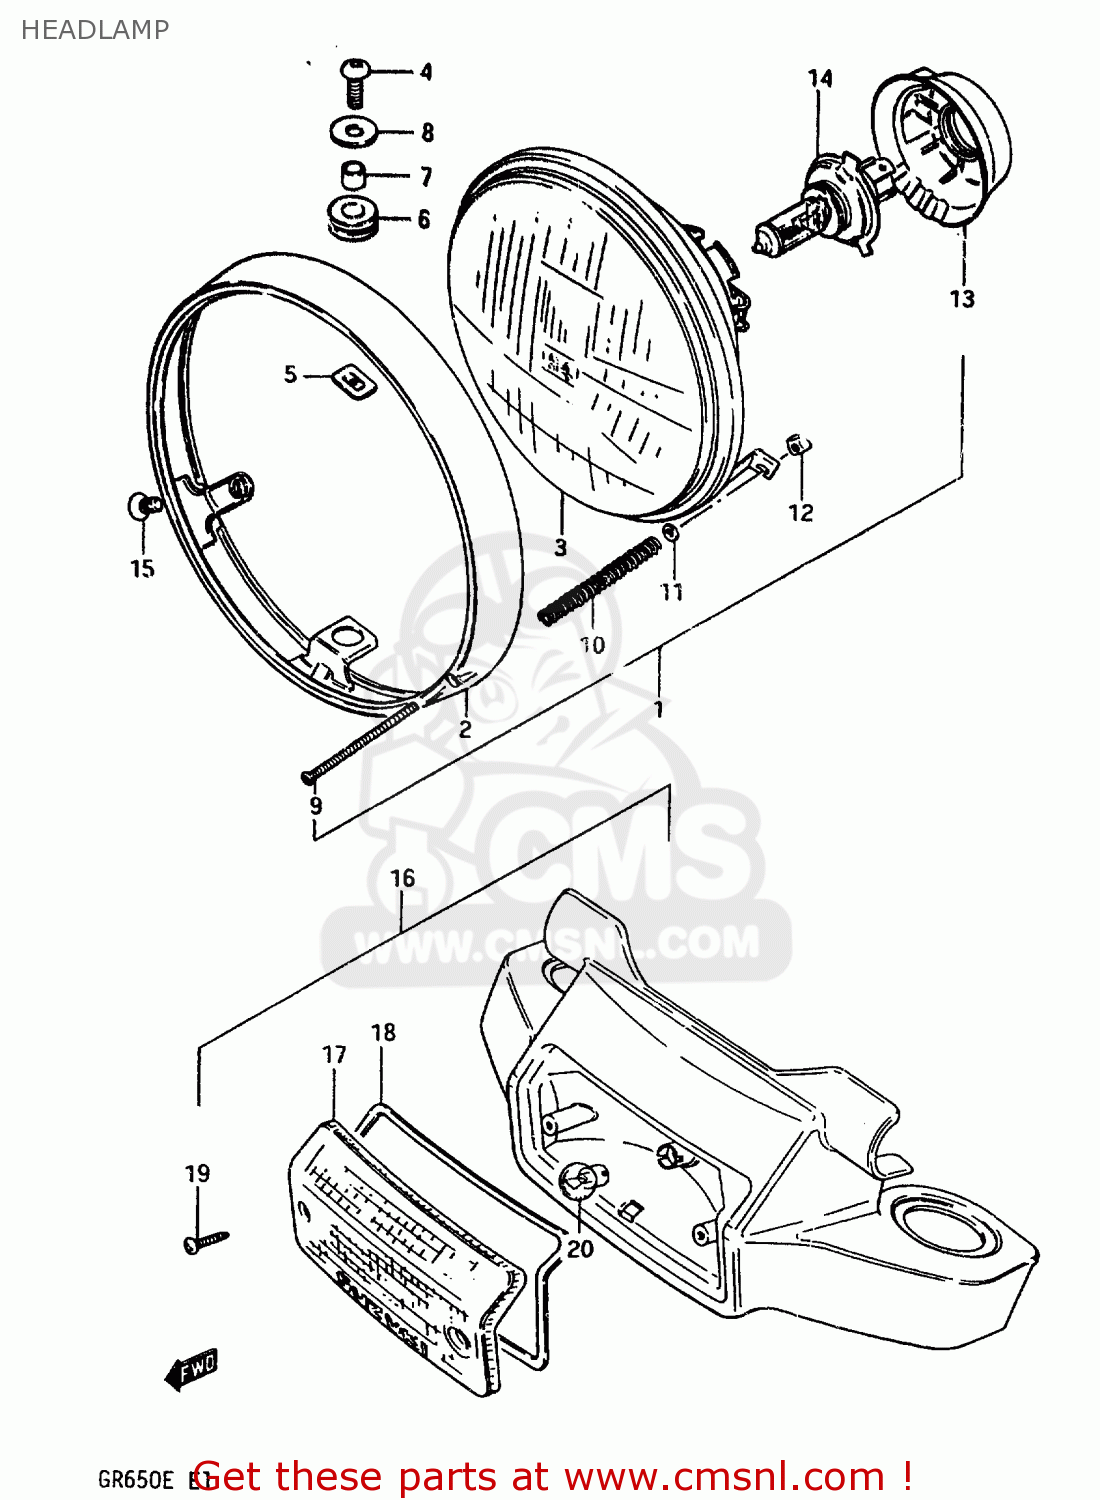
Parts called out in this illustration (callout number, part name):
1	LAMP ASSEMBLY,HEAD
2	RIM,HEAD LAMP
3	LAMP UNIT
4	SCREW(5X14)
5	NUT
6	CUSHION
7	SPACER
8	WASHER
9	SCREW,HEADLAMP ADJUST
10	SPRING,HEADLAMP ADJUST
11	WASHER
12	NUT
13	COVER,SOCKET
14	BULB(12V60/55W,H4)
15	SCREW(5X12)
16	LAMP ASSY, FRONT POSITION
17	LENS
18	GASKET,POSITION LAMP
19	SCREW,POSITION LENS
20	BULB
